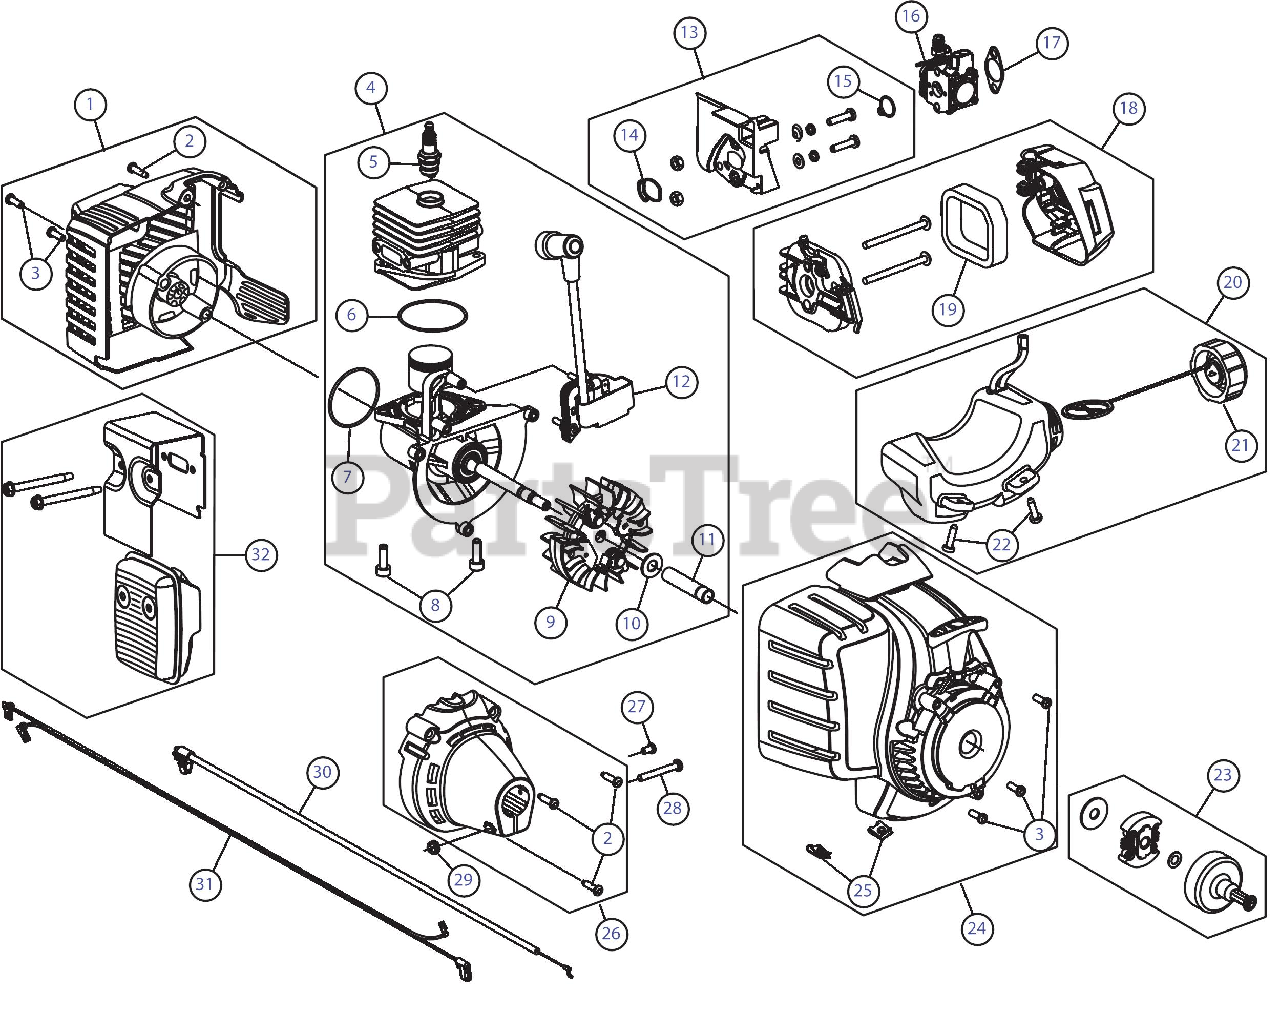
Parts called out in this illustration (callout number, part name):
1	Rear Cover Assembly (includes 2 & 3)
2	Cover Screw
3	Rear Housing Screw
4	Short Block Assembly (includes 5 - 12)
5	Spark Plug
6	Crankcase O-Ring
7	O-Ring
8	Crankcase Bolt
9	Flywheel Assembly
10	Washer
11	Spacer
12	Module Assembly
13	Insulator Assembly (includes 14 & 15)
14	Insulator O-Ring
15	Carburetor O-Ring
16	Carburetor
17	Air Cleaner Gasket
18	Air Cleaner Cover Assembly (includes 19)
19	Air Cleaner Filter
20	Fuel Tank Assembly (includes 21 & 22)
21	Fuel Tank Cap
22	Fuel Tank Screw
23	Clutch Assembly
24	Starter Housing (includes 3 & 25)
25	U-shaped Nut
26	Clutch Cover (includes 2)
27	Anti-rotation Screw
28	Clamp Screw
29	Clamp Nut
30	Throttle Cable
31	Lead Wires
32	Muffler Assembly
